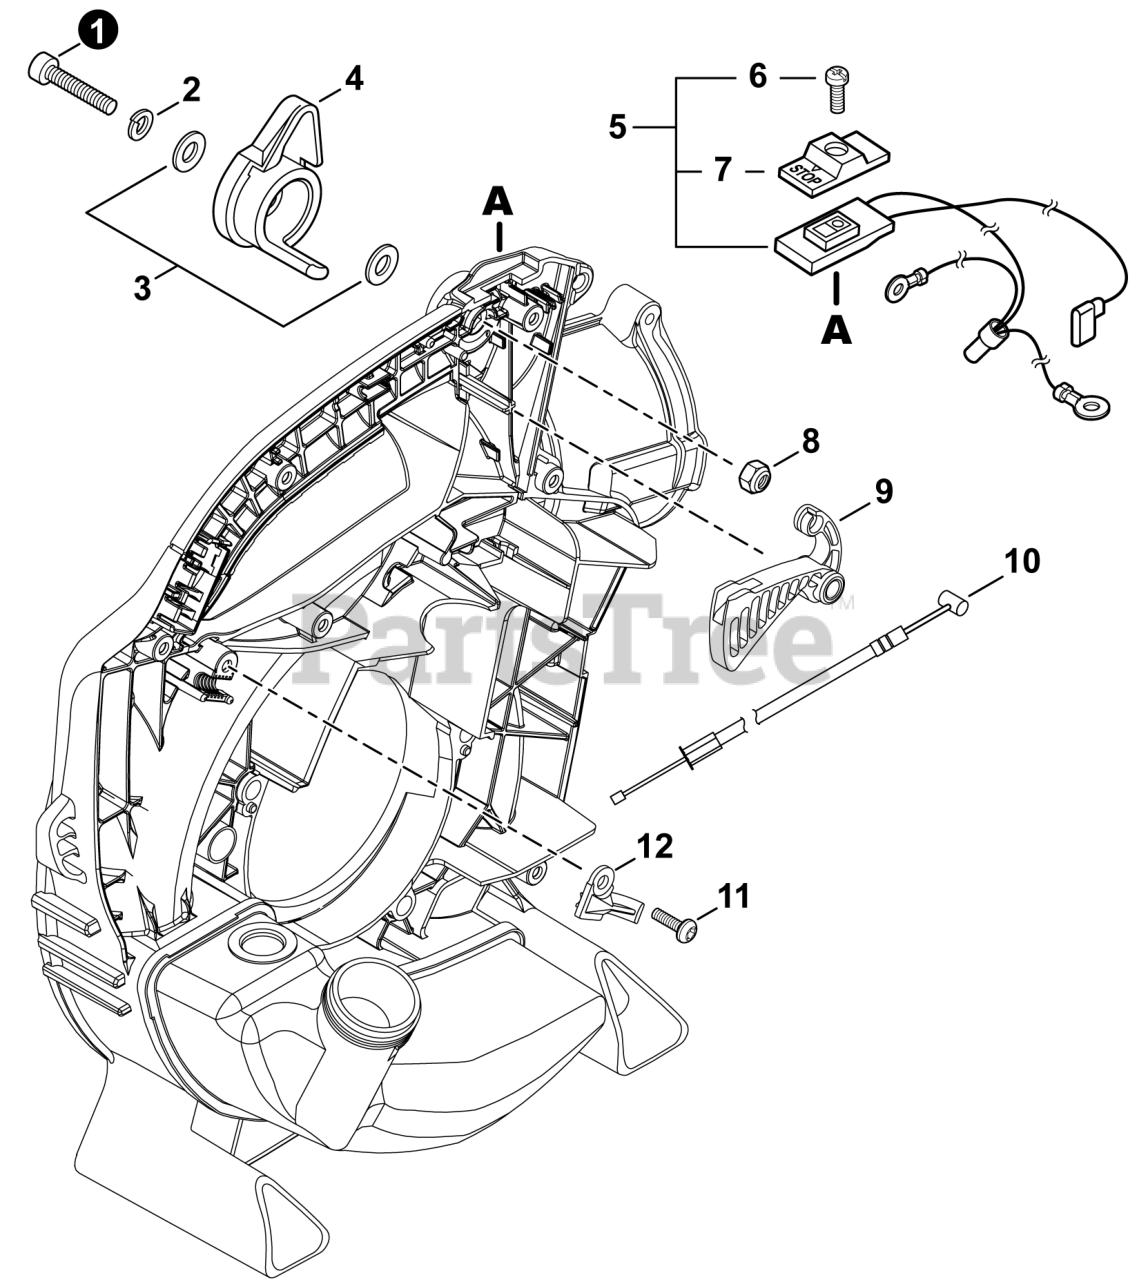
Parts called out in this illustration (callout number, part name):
1	BOLT, TORX 5x25
2	WASHER, SPRING 5
3	WASHER 5.5x12x0.8
4	CONTROL, THROTTLE
5	SWITCH, ON-OFF
6	SCREW 3x10
7	KNOB, SWITCH
8	NUT, LOCK M5
9	TRIGGER, THROTTLE
10	CABLE, THROTTLE
11	BOLT, TORX 5x12
12	GUIDE, CABLE
